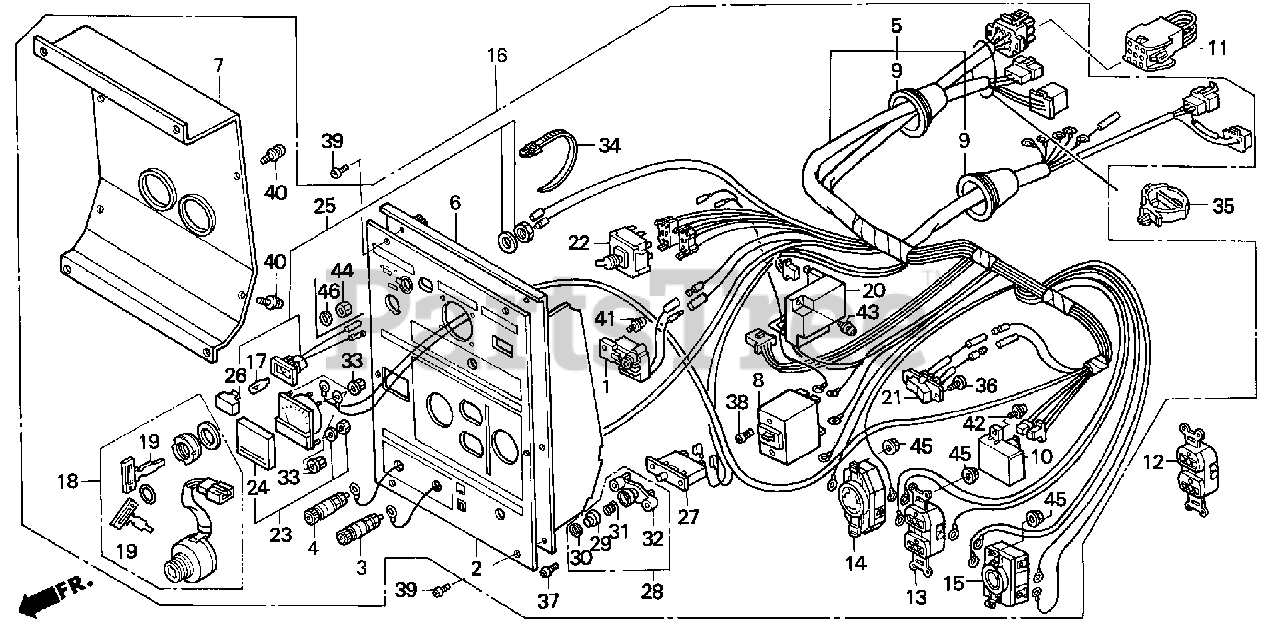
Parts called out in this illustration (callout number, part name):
1	ALERT UNIT, OIL
2	MARK, CONTROL INDICATION
3	TERMINAL, D.C. OUTPUT (+)
4	TERMINAL, D.C. OUTPUT (-)
5	HARNESS ASSY., CONTROL
6	PANEL, CONTROL
7	COVER, CONTROL
8	BREAKER, CIRCUIT (13.5A)
9	GROMMET, MAIN WIRE
10	DIODE ASSY.
11	CONNECTOR ASSY.
13	RECEPTACLE (20A/125V) (MATSUSHITA)
14	RECEPTACLE (30A/125V)
15	RECEPTACLE (20A-125/250V) (MATSUSHITA)
16	PANEL ASSY., CONTROL
17	BULB, WEDGE BASE (12V/2W)
18	SWITCH ASSY., COMBINATION
19	KEY
20	THROTTLE UNIT, AUTO (SAWAFUJI)
21	SWITCH, AUTO THROTTLE
22	SWITCH ASSY., VOLT CHANGE
23	METER ASSY., VOLT (300V)
24	LENS, METER
25	SOCKET ASSY., LAMP (GREEN)
26	LENS (GREEN)
27	PROTECTOR, CIRCUIT (D.C.)
28	LENS ASSY., PROTECTOR
31	SPRING, COIL
32	HOLDER, LENS
33	NUT, FLANGE (3MM)
34	TIE, CABLE
35	STRAP, WIRE HARNESS (25MM) (BLACK)
36	SCREW, PAN (3X6)
37	SCREW, PAN (3X12)
38	SCREW, PAN (4X6)
39	SCREW, PAN (5X10)
40	SCREW-WASHER (4X8)
41	SCREW-WASHER (4X10)
42	SCREW-WASHER (4X12)
43	SCREW-WASHER (5X12)
45	NUT, FLANGE (4MM)
